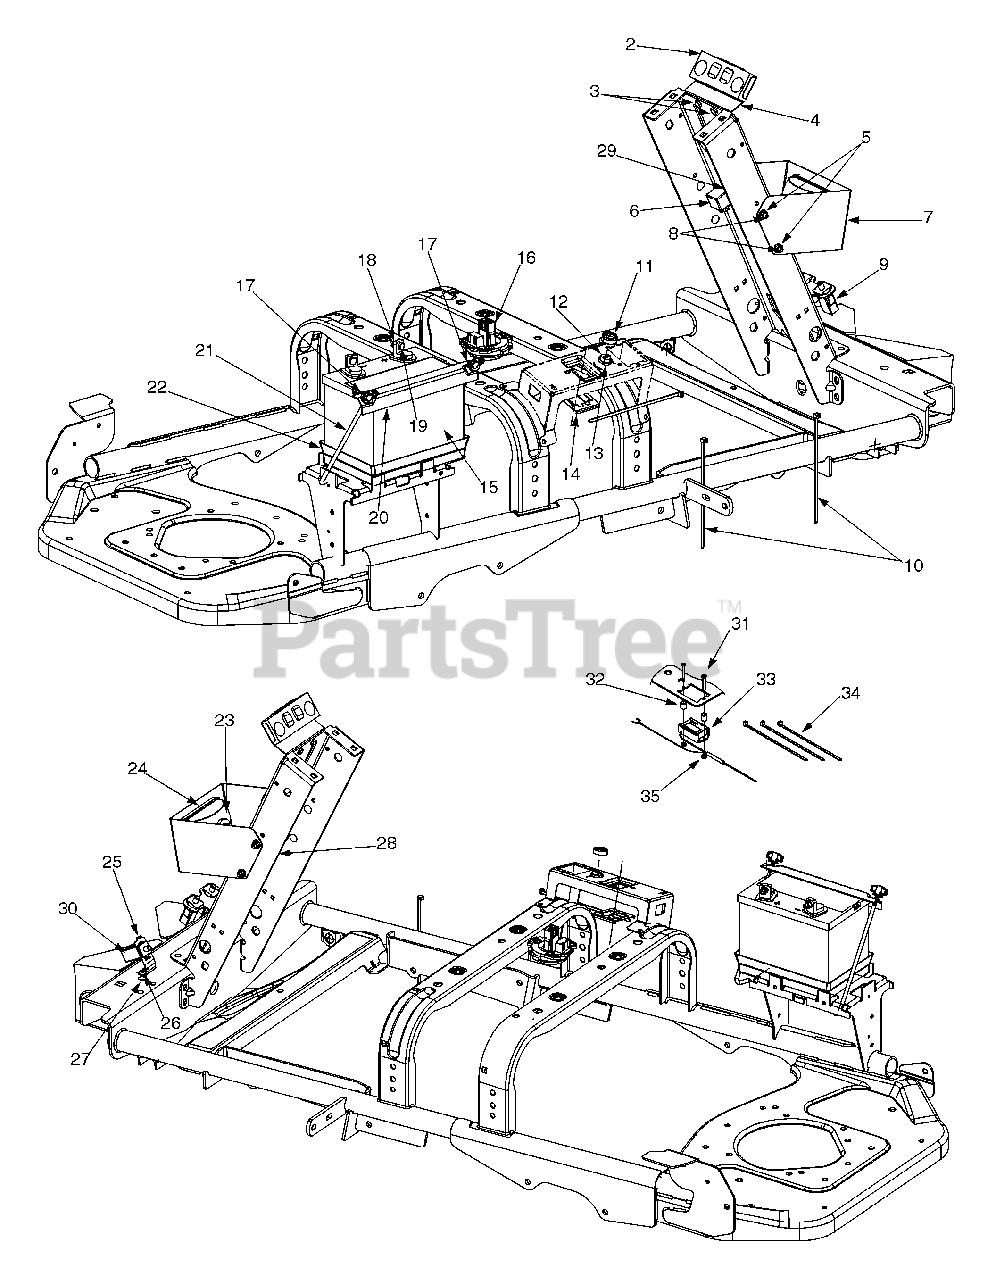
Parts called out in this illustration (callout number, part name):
2	Foam Protector, Indicator Light
3	Hex Cap Screw 1/4-20 x .50
6	Relay
9	Switch, Plunger Safety
10	Cable Tie
11	Cap, Ignition Switch
12	Nut, Ignition Switch, 5/8-32
13	Switch, Ignition
14	Bracket, PTO Switch Retainer
16	Switch, Seat
17	Nut, Nylon Wing, 1/4-20
18	Nut, Hex Sems, 1/4-20
19	Screw, Hex Cap, 1/4-20 x .75 GR5
20	Strip, Battery Retainer
21	Rod, Battery Retainer
22	Tray, Battery
23	Headlight Assembly
24	Bezel, Headlight
25	Spring, Switch Mounting
26	Screw, Machine, #10-24 x 5/8
27	Nut, Hex Insert Lock, #10-24
28	Voltage Sensor
29	Ratchet Retainer
30	Switch, Plunger Safety
31	Machine Screw #10-24
32	Spacer .315 ID x .50 OD
33	Hour Meter
34	Cable Tie
35	Lock Nut #10-24
